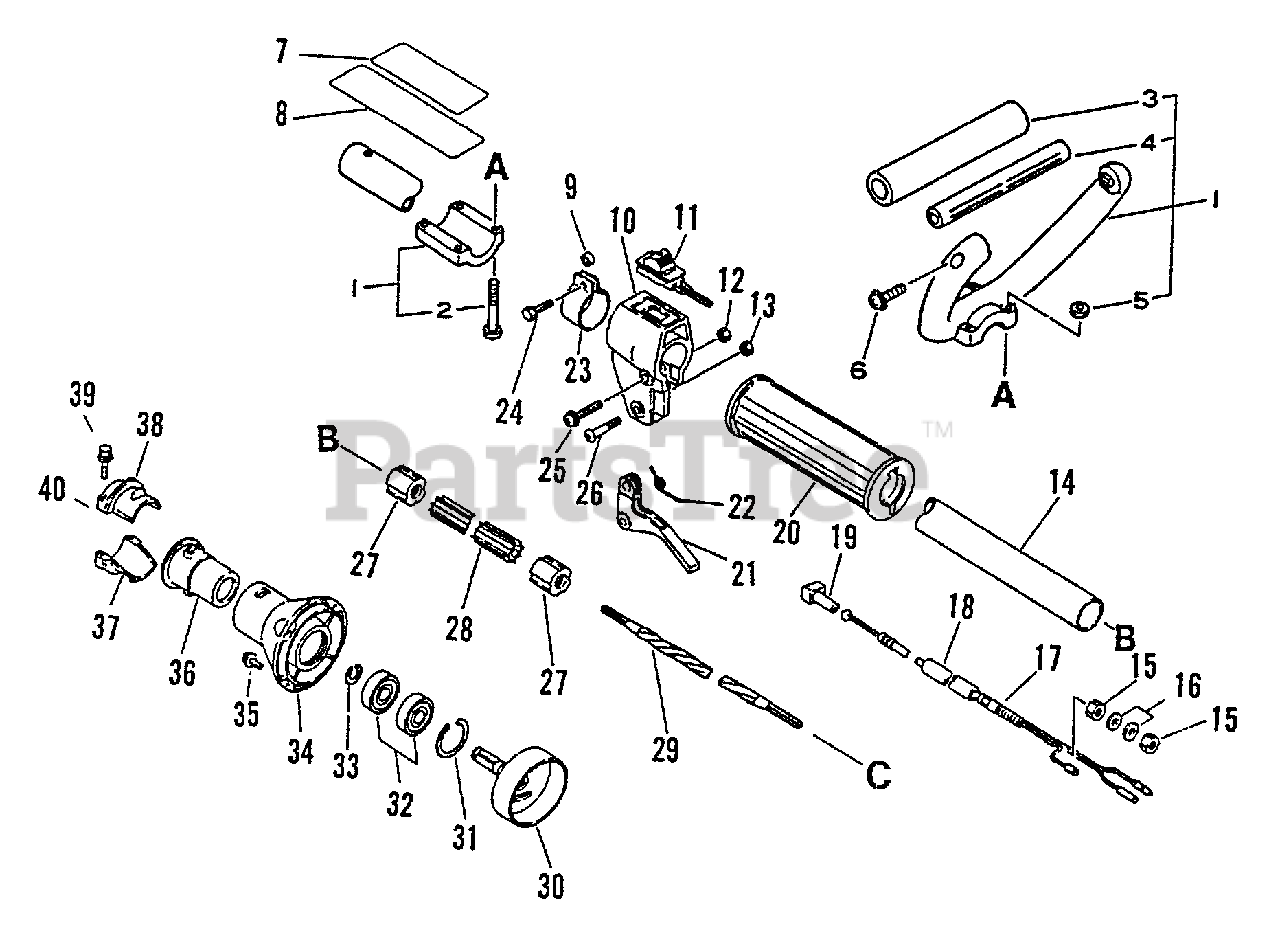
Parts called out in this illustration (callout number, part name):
1	LOOP HANDLE ASSY
2	SCREW - 5X35
3	GRIP, HANDLE
6	SCREW - 5X30
7	LABEL - CAUTION
8	LABEL - CAUTION
10	BRACKET, THROTTLE CONTROL
11	IGNITION SWITCH ASSY
13	LOCKNUT - 5
14	MAIN PIPE ASSY
16	WASHER - 6
17	CABLE, THROTTLE
18	TUBE - VINYL
19	GUIDE, CABLE
20	GRIP, HANDLE
21	TRIGGER, THROTTLE
22	SPRING, TRIGGER
24	BOLT - 5X18
25	SCREW - 5X30
26	SCREW - 5X30
28	LINER - FLEXIBLE
29	DRIVESHAFT - FLEXIBLE
30	DRUM, CLUTCH
31	RING, RETAINING - 28
32	BEARING, BALL - 6001
33	RING, RETAINING - 12
34	CASE, CLUTCH - GRAY
35	SCREW - 5X16
37	CLAMP, MAIN PIPE
38	CLAMP, MAIN PIPE - UPPER
39	BOLT - 5X25
40	HOLDER KIT
